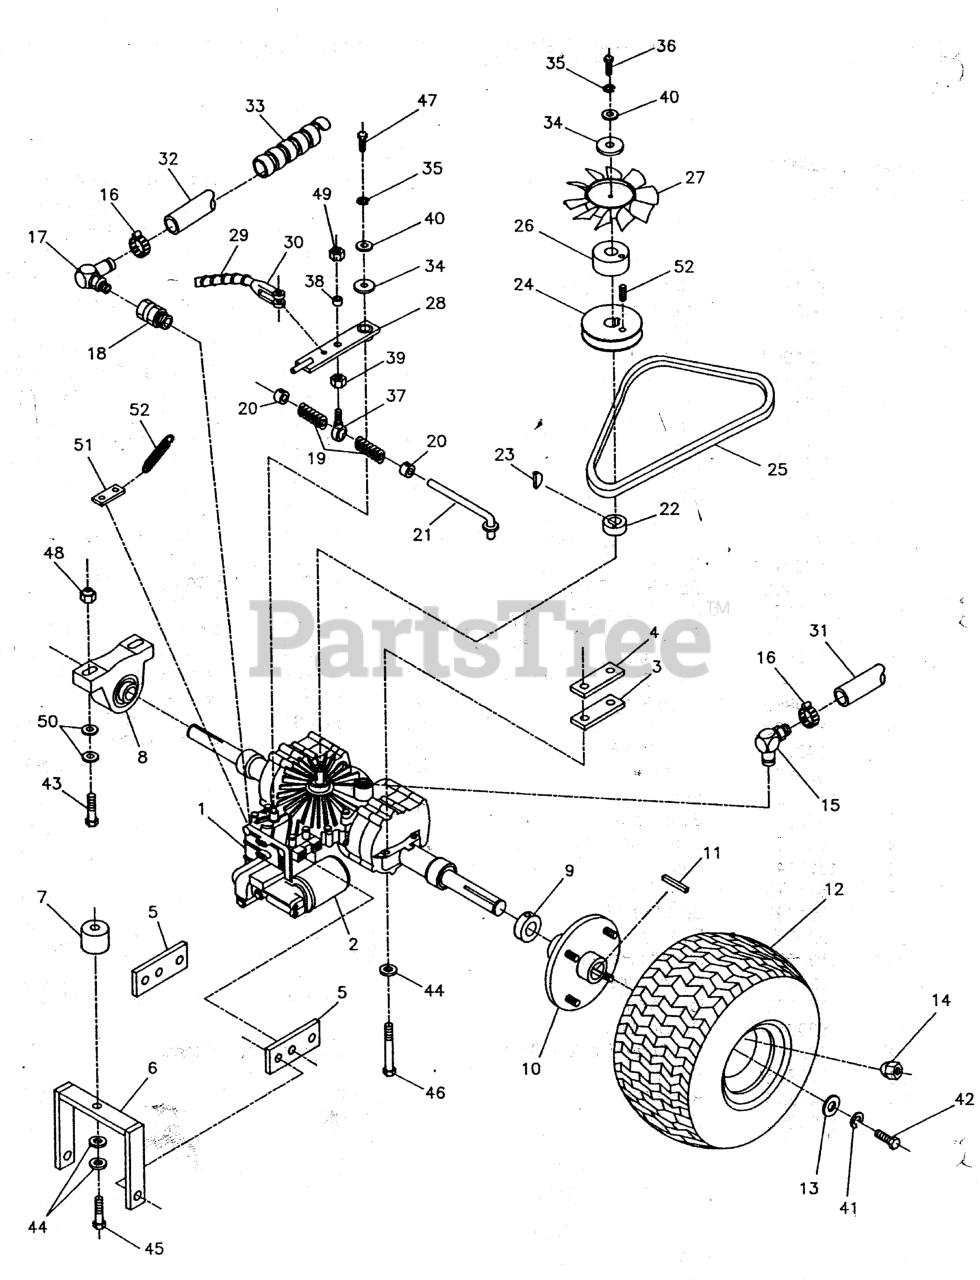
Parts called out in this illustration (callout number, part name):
1	850 Transaxle
1	Transmission
2	FILTER, Transmission Oil
3	3/16" Spacer (Black)
4	1/4" Spacer (Red)
5	BRACKET, Transmission Support
6	Transmission Torque Bracket
7	SPACER, .39 x 1.75 x .88
8	BEARING, PILLOW BLOCK, 1
9	COLLAR, 1" Split
10	DRIVE HUB DETAIL
11	KEY, 1/4 SQ. X 2-1/2
12	TIRE & WHEEL ASSEMBLY, 18 X 8.5 X 8
12	WHEEL & TIRE ASSEMBLY, 20 x 10 x 8, Complete
13	Retaining Spacer
13	RING, Retaining
14	LUG NUT, 1/2-20
15	FITTING, 90 Degrees 7/8" O-Ring
16	CLAMP, #10 Hose
17	FITTING, 90 Degrees 1/2" NPT
18	FITTING, 7/8" O-Ring Straight Swivel
19	SPRING, Compression
20	COLLAR, 5/16" Set
21	ROD, NEUTRAL SPRING WELDMENT
22	Hydro Input Pulley Spacer
22	SPACER, .67 x 1.25 x .50
23	KEY, #61 Woodruff
24	PULLEY (3/4" Bore)
24	Pulley 17mm Bore
25	BELT, A-Section
26	Fan Pulley Spacer
28	TRANSMISSION CONTROL ARM
29	CABLE, Speed Control
30	5/16" Rod End Clevis
31	Return Hose
32	Inlet Hose
33	Plastic Hose Protector
34	WASHER, 5/16" Fender
35	WASHER, 1/4 LOCK
36	BOLT, 1/4-20 x 1-3/4
37	BALL JOINT, 3/8-24 Male
38	SPACER, .38 x .50 x .27
39	NUT, 3/8-24 Hex
40	WASHER, 1/4 SAE
41	WASHER, 3/8" Lock
42	BOLT, 3/8-16 X 1-1/4" GD5 CZ
43	BOLT, 3/8-16 X 1-1/2" GD5 CZ
44	WASHER, 3/8 SAE
45	BOLT, 3/8-16 X 2, GD5, CZ
46	BOLT, 3/8-16 X 3-1/2" GD5 CZ
47	BOLT, 1/4-20 x 1-1/2
48	NUT, 7/16-20 Hex Nylon Lock
49	NUT, 3/8-24 Hex Nylon Lock
50	WASHER, 7/16" SAE
51	Dump Valve Lever
52	SPRING, Extension
